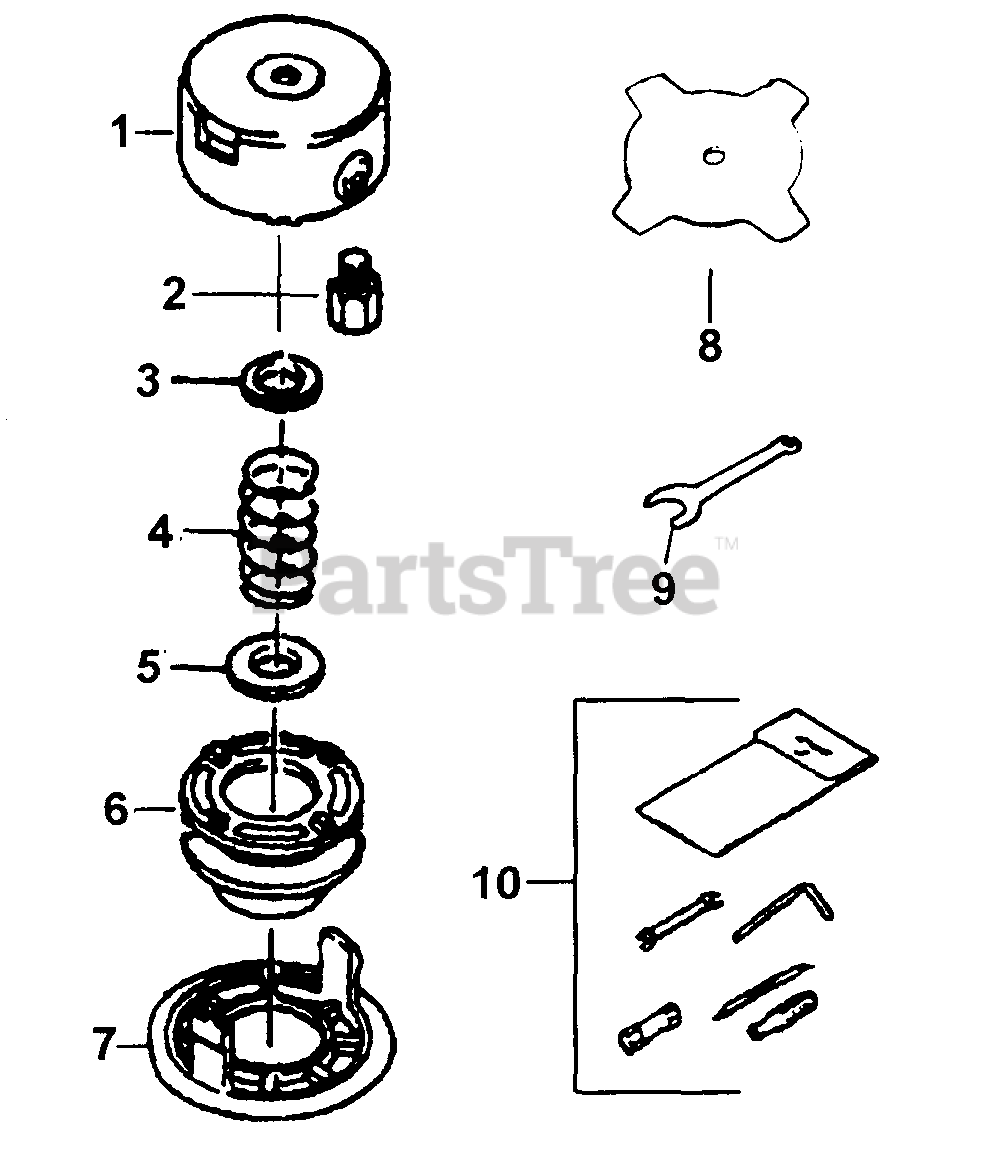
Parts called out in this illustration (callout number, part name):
1	6" HEAD BODY
2	ARBOR BOLT
3	SPRING PLATE
4	SPRING
5	PLATE, SPRING
7	6" CAP
8	QUAD BLADE
9	SPANNER WRENCH
